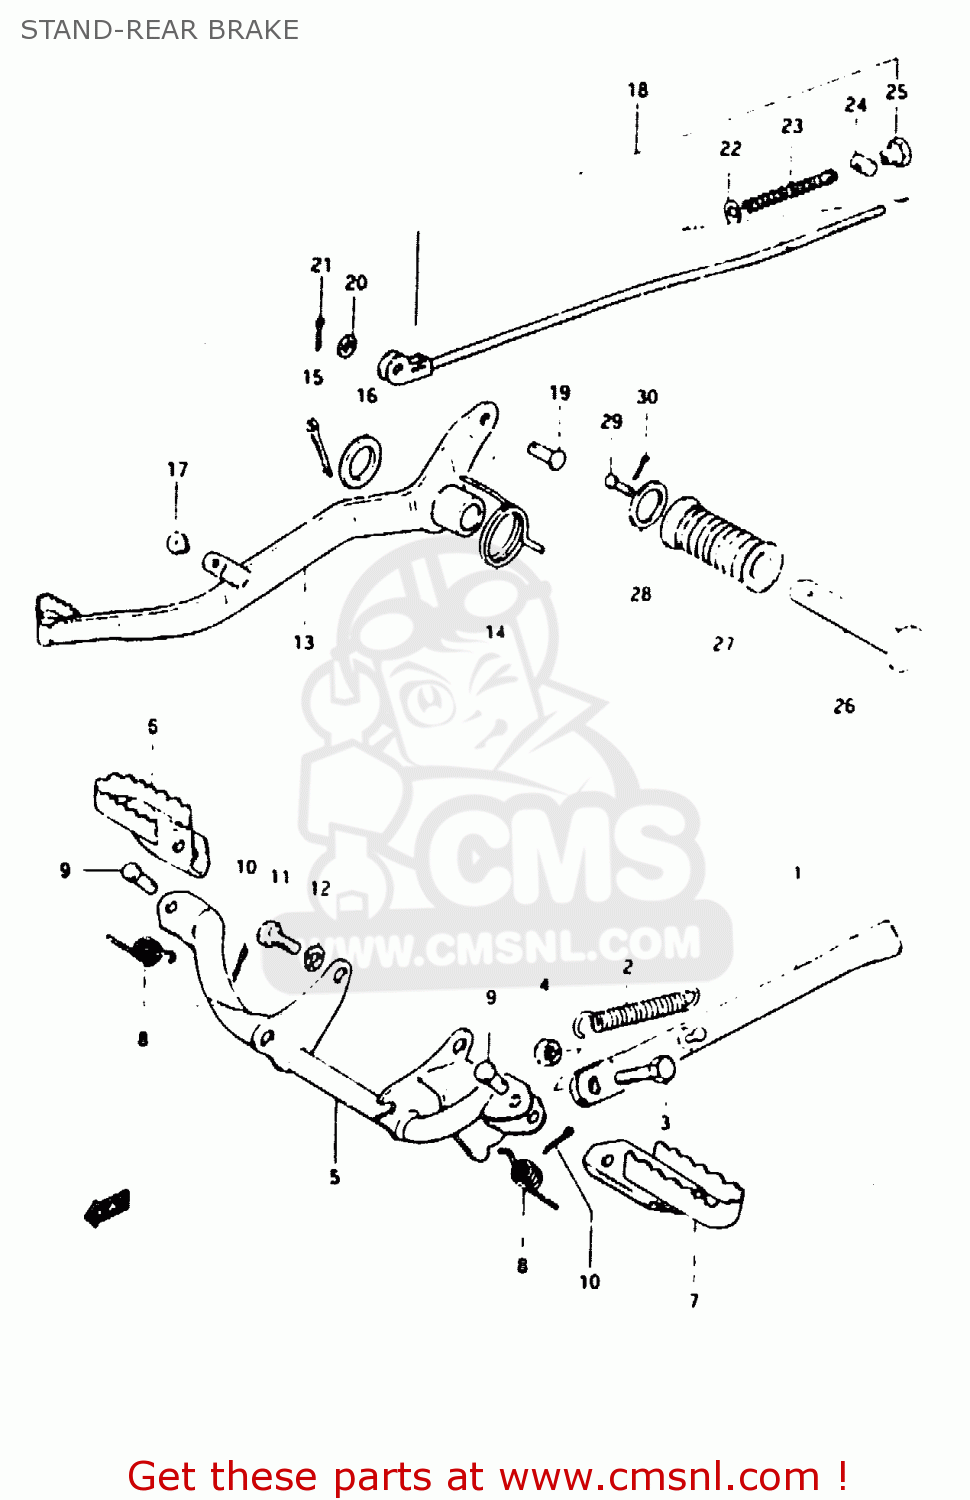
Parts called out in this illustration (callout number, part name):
1	STAND, PROP
2	SPRING
3	BOLT
4	NUT
5	BAR, FRONT FOOTREST
6	FOOTREST,FRONT,RIGHT
7	FOOTREST
8	SPRING
9	PIN
10	PIN 20X20
11	BOLT
12	LOCK WASHER
13	PEDAL, BRAKE
14	SPRING
15	COTTER PIN
16	WASHER(15.5X26X2.3)
17	STOPPER,BRAKE PEDAL
18	ROD ASSEMBLY,REAR BRAKE
19	PIN(L:13.5)
20	WASHER
21	PIN 20X20
22	WASHER
23	SPRING
24	PIN(11X18)
25	NUT
26	BAR,FOOTREST RUBBER
27	RUBBER,PILLION FOOTREST
28	WASHER (19.5X32X2)
29	PIN
30	PIN 20X20
